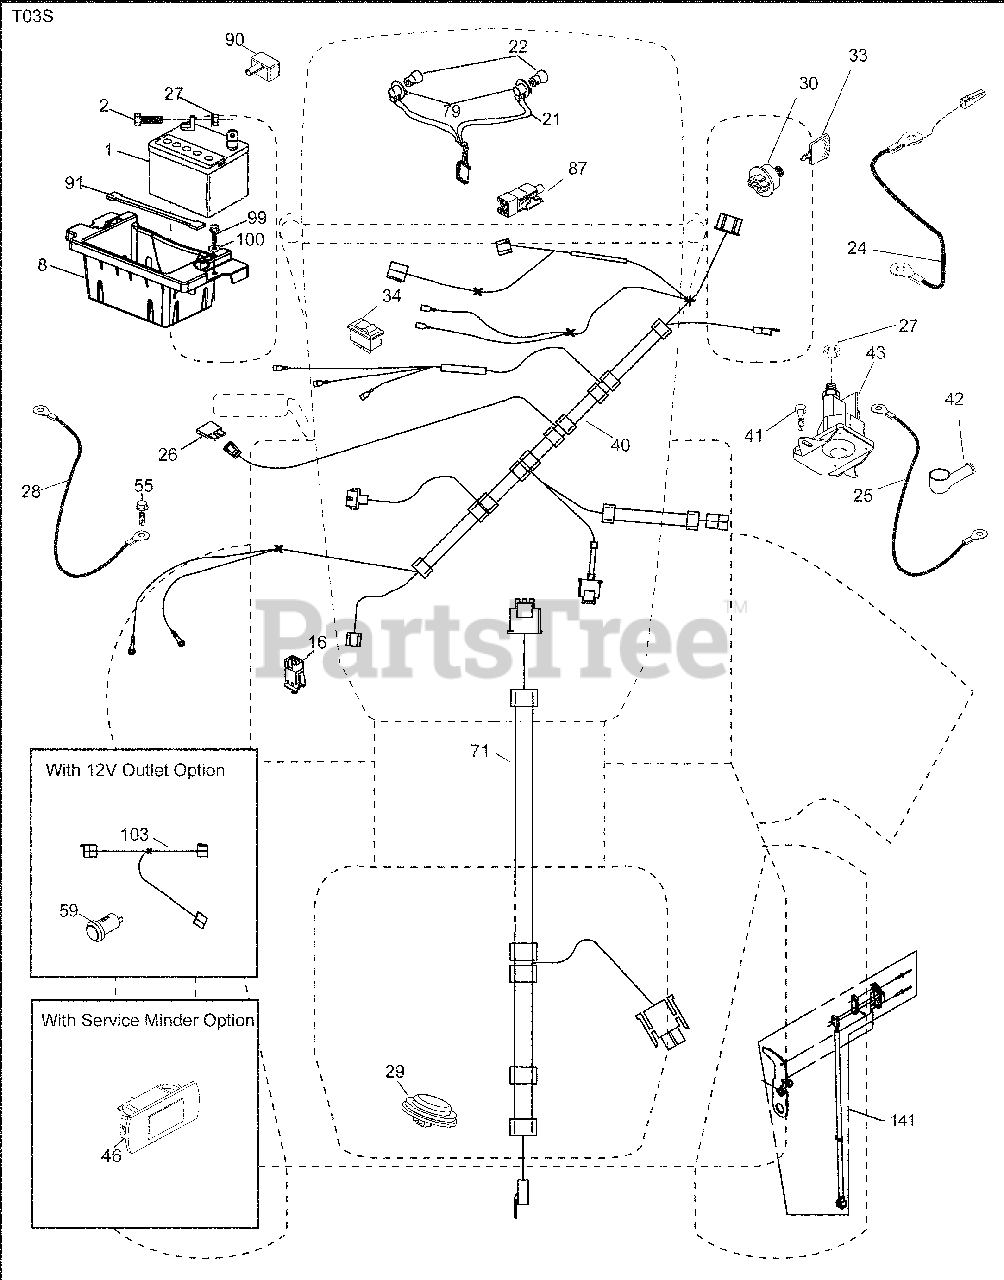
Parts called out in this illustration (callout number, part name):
1	Battery
2	Bolt Hex Head 1/4-20 x 3/4
8	Box Battery
16	Switch Interlock Push-In
21	Harness Socket Light w/4152J
22	Bulb Light
24	Cable Battery
25	Cable Starter
27	Nut Keps Hex 1/4-20 unc
28	Cable, Ground
29	Switch, Seat
30	Switch, Ign
33	Key/Chain
34	Switch Light/Reset
40	Harness Ign. Dash
41	Screw Thd Cut 1/4-20 x 1/2
42	Cover, Terminal
43	Solenoid
46	Gauge Servicereminder Hrmtr
55	Screw Thdrol 5/16-18 x 3/4 TYTT
71	Harness Ign.
79	Socket Asm. Bulb
87	Switch Interlock
90	Cover Terminal
91	Strap Battery Mount Front
99	Screw 1/4-20 x 3/4
100	Washer 9/32 x 7/8 x 16 Ga.
141	Kit T2 ROS
